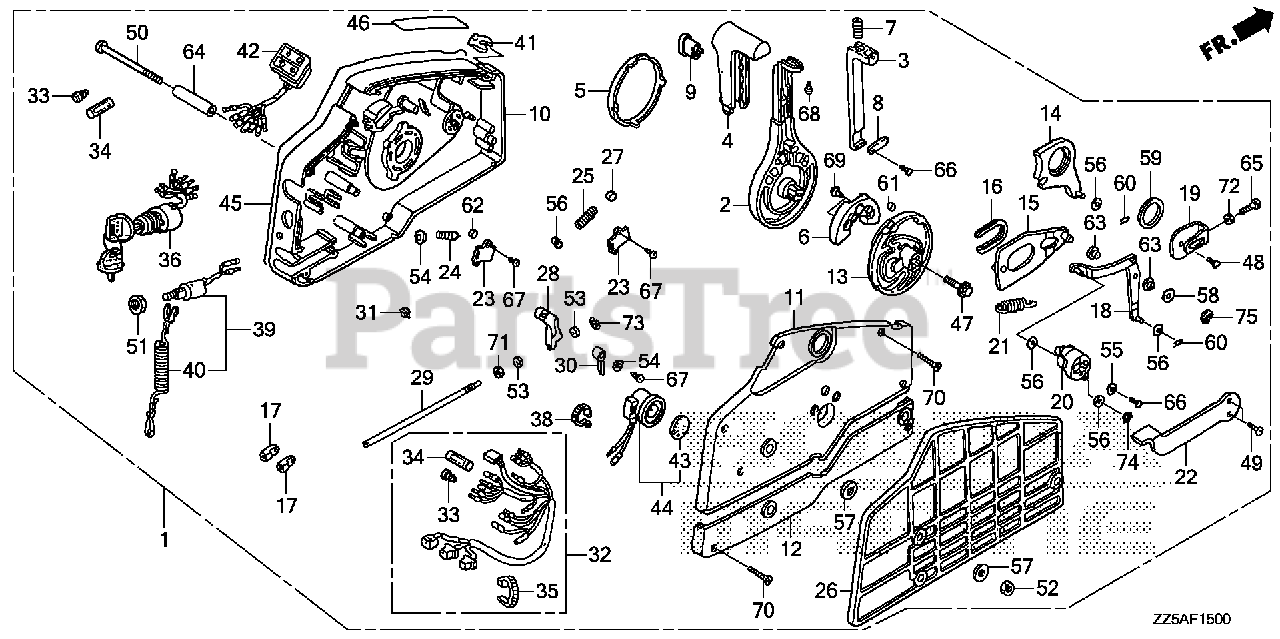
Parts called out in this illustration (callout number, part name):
1	BOX ASSY., REMOTE CONTROL (HI-LEX)(A/T)
2	HANDLE, REMOTE CONTROL
3	LEVER, HANDLE LOCK
4	GRIP, REMOTE CONTROL HANDLE
5	CAP, HANDLE
6	BLOCK, NEUTRAL LOCK
7	SPRING, REMOTE CONTROL HANDLE
8	PLATE, LEVER SETTING
9	COVER, GRIP
10	HOUSING, REMOTE CONTROL BOX (A)
11	HOUSING, REMOTE CONTROL BOX (B)
12	HOUSING, REMOTE CONTROL BOX (C)
13	WHEEL, CONTROL
14	ARM, SHIFT LINK
15	PLATE, SLIDING
16	COLLAR, SLIDING PLATE
17	PIVOT, SHIFT
18	ARM, LINK JOINT
19	BRACKET, LINK JOINT
20	WHEEL, ACCELERATOR
21	SPRING, ACCELERATOR WHEEL
22	LEVER, IDLE
23	PLATE, SPRING SETTING
24	SPRING, SHIFT CLICK
25	SPRING, CHOKE RETURN
26	SPACER, REMOTE CONTROL BOX
27	SPACER, CLICK SPRING
28	BLOCK, THROTTLE FRICTION
29	BOLT, FRICTION
30	SPACER, NEUTRAL SWITCH
31	SPACER, CABLE CLAMP
32	CABLE ASSY., REMOTE CONTROL (B)
33	PLUG, CONNECTOR (INNER)
34	PLUG, CONNECTOR (OUTER)
35	TIE, CABLE (2.4X92) (NATURAL)
36	SWITCH ASSY., COMBINATION
38	BAND (BLACK 3.5X140)
39	SWITCH ASSY., EMERGENCY STOP
40	WIRE, EMERGENCY
41	CLIP, EMERGENCY LOCK
42	LAMP ASSY., INDICATION
43	PLATE, TURN SIGNAL BUZZER
44	BUZZER, WARNING
45	PLATE, REMOTE CONTROL (COUTION COLOR=RED & YELLOW)
46	MARK, FAST IDLE
47	BOLT, FLANGE (8X35)
48	SCREW, PAN (6X10)
49	SCREW, FLAT (5X12)
50	SCREW (6X95)
51	NUT, HEX. (16MM)
52	NUT, HEX. (6MM)
53	WASHER, PLAIN (4MM)
54	WASHER, PLAIN (5MM)
55	WASHER, PLAIN (5MM)
56	WASHER, PLAIN (6MM)
57	WASHER (6MM)
58	WASHER, PLAIN (8MM)
59	WASHER (28MM)
60	PIN, LOCK (6MM)
61	PIN (6X6)
62	ROLLER, CLICK
63	COLLAR, LINK JOINT
64	COLLAR, DISTANCE (6X10X43.5)
65	BOLT, HEX. (5X16)
66	SCREW, PAN (5X10)
67	SCREW, TAPPING (5X10)
68	SCREW, TAPPING (5X12)
69	SCREW, TAPPING (6X16)
70	SCREW, TAPPING (5X25)
71	NUT, HEX. (6MM)
72	NUT, HEX. (5MM)
73	E-RING (3MM)
74	E-RING (4MM)
75	E-RING (7MM)
